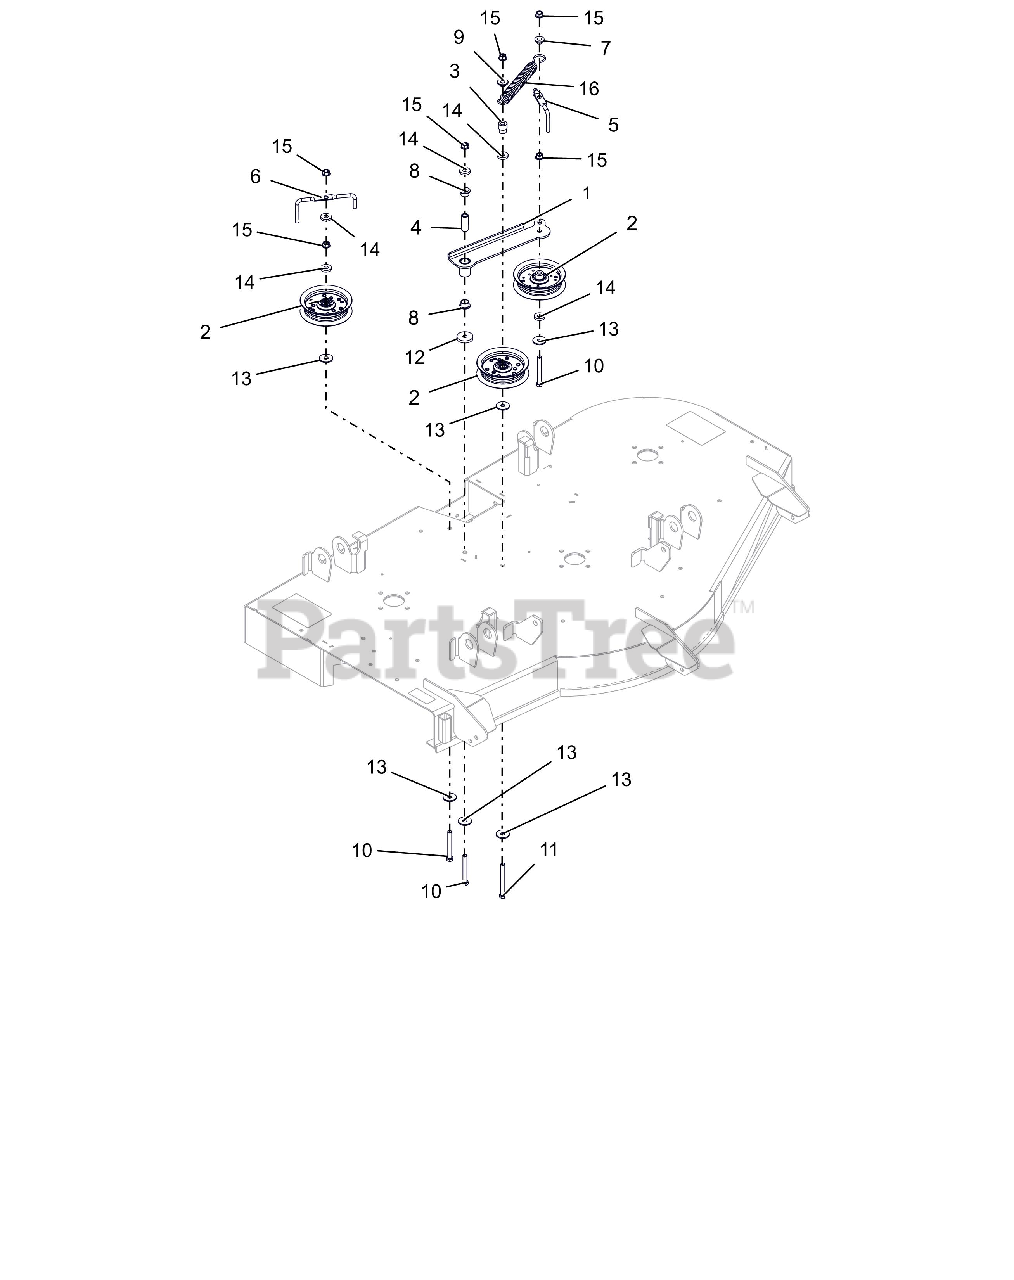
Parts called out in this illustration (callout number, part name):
1	WLDMT, IDLER ARM-52"
2	ASM, IDLER 4"
3	BUSHING, IDLER (P/M)
4	SPACER, .375IDX.625ODX1.66 PM
5	WIREFORM, BELT FINGER
6	WIREFORM, BELT FINGER
7	BSHG-FLG .385X.500X.875X.406
8	BSHG-FLG, .625X.750X.500X1.00
9	BSHG-FLG .385X.500X.875X.31
10	BLT-HEX .38-16X3.00 GR5 FTH YZ
11	@BLT-HEX .38-16X3.50 GR5 YWZC
12	WSHR,FLT STL.406X1.50X.245YWZC
13	@WSHR-FL-STL .406X1.25X.10 ZC
14	WSHR-FL-STL .406X1.00X.188 YWZ
15	@NUT-LK-TOP-FLG .38-16 YWZC
16	SG-TENS .135X.98X6.0 WLD 62
